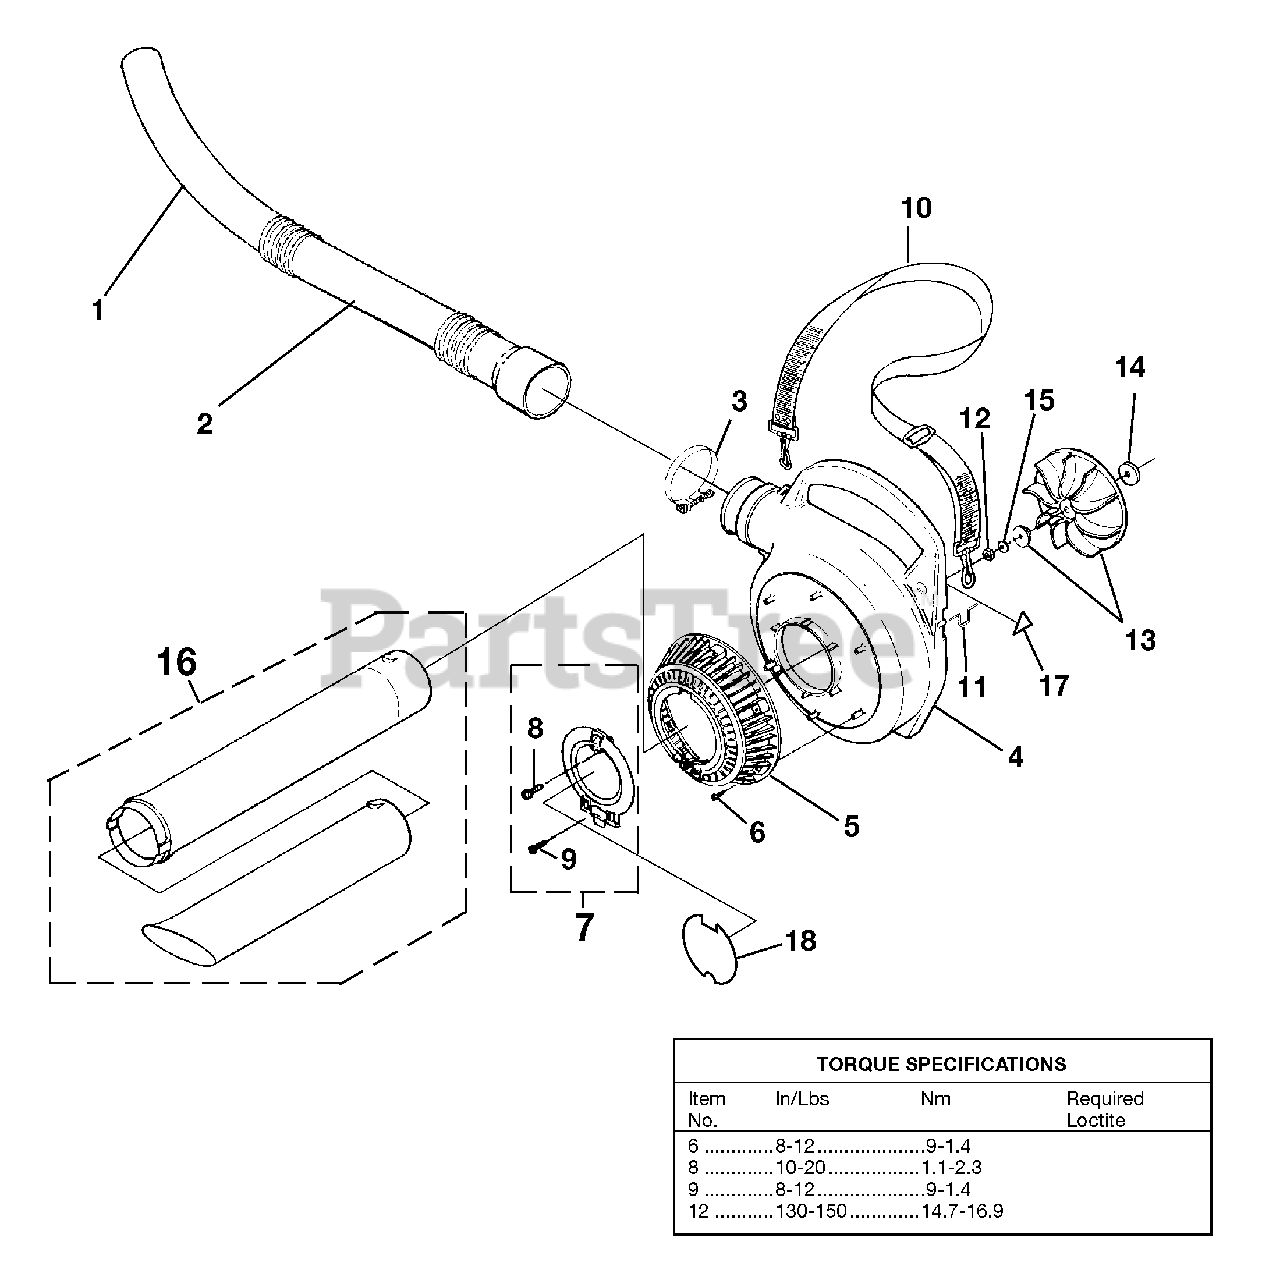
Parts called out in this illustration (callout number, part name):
1	NOZZLE, ROUND
2	TUBE, UPPER YB
3	CLAMP w/Fasteners
4	OUTER VOLUTE HOUSING
5	BLOWER VAC GRILLE
6	SCREW-Thread Form. (#6 X 3/8)
7	ACCESS DOOR KIT
8	SCREW-Thread Rolling (#10 X 5/8)
9	SCRE W-Thread Form. (#8 X 1/2)
10	SHOULDER STRAP
11	WIRE LOOP
12	NUT-Hex (3/8-24)
13	BLOWER FAN KIT
14	WASHER-Flat
15	WASHER-Bellville (3/8)
16	TUBE Kit w/Decals(Vacuum units only)
17	DECAL-Idle Adjustment
18	DECAL-Model ID
